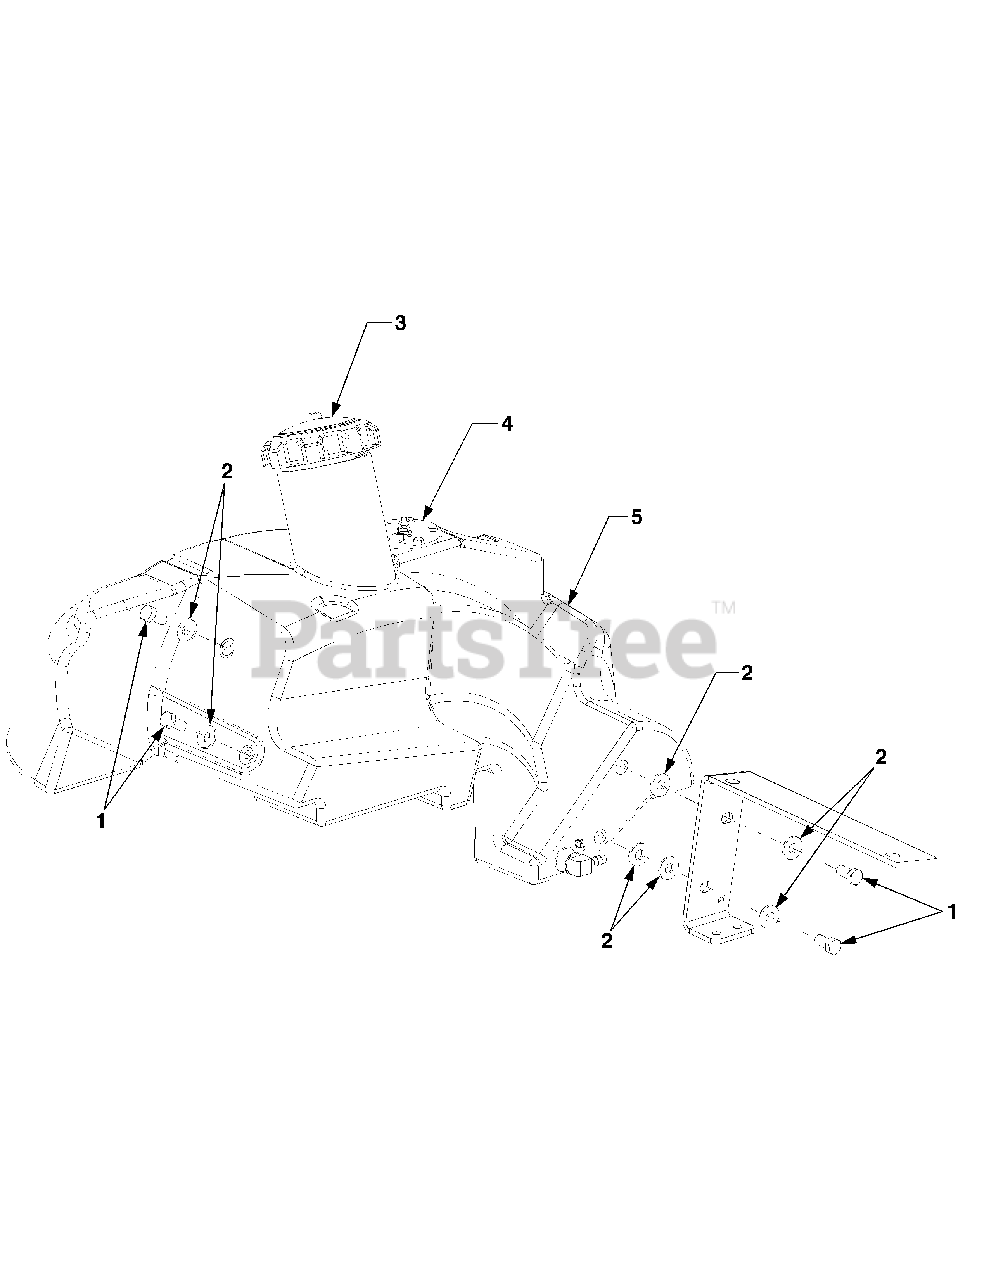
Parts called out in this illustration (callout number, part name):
1	Screw, Hex Cap, Lock 3/8-16 x .75 GR5
2	Washer, Flat, .385 x .87 x .092
3	Cap, Fuel
4	Sensor, Fuel Level
5	Tank, Fuel
